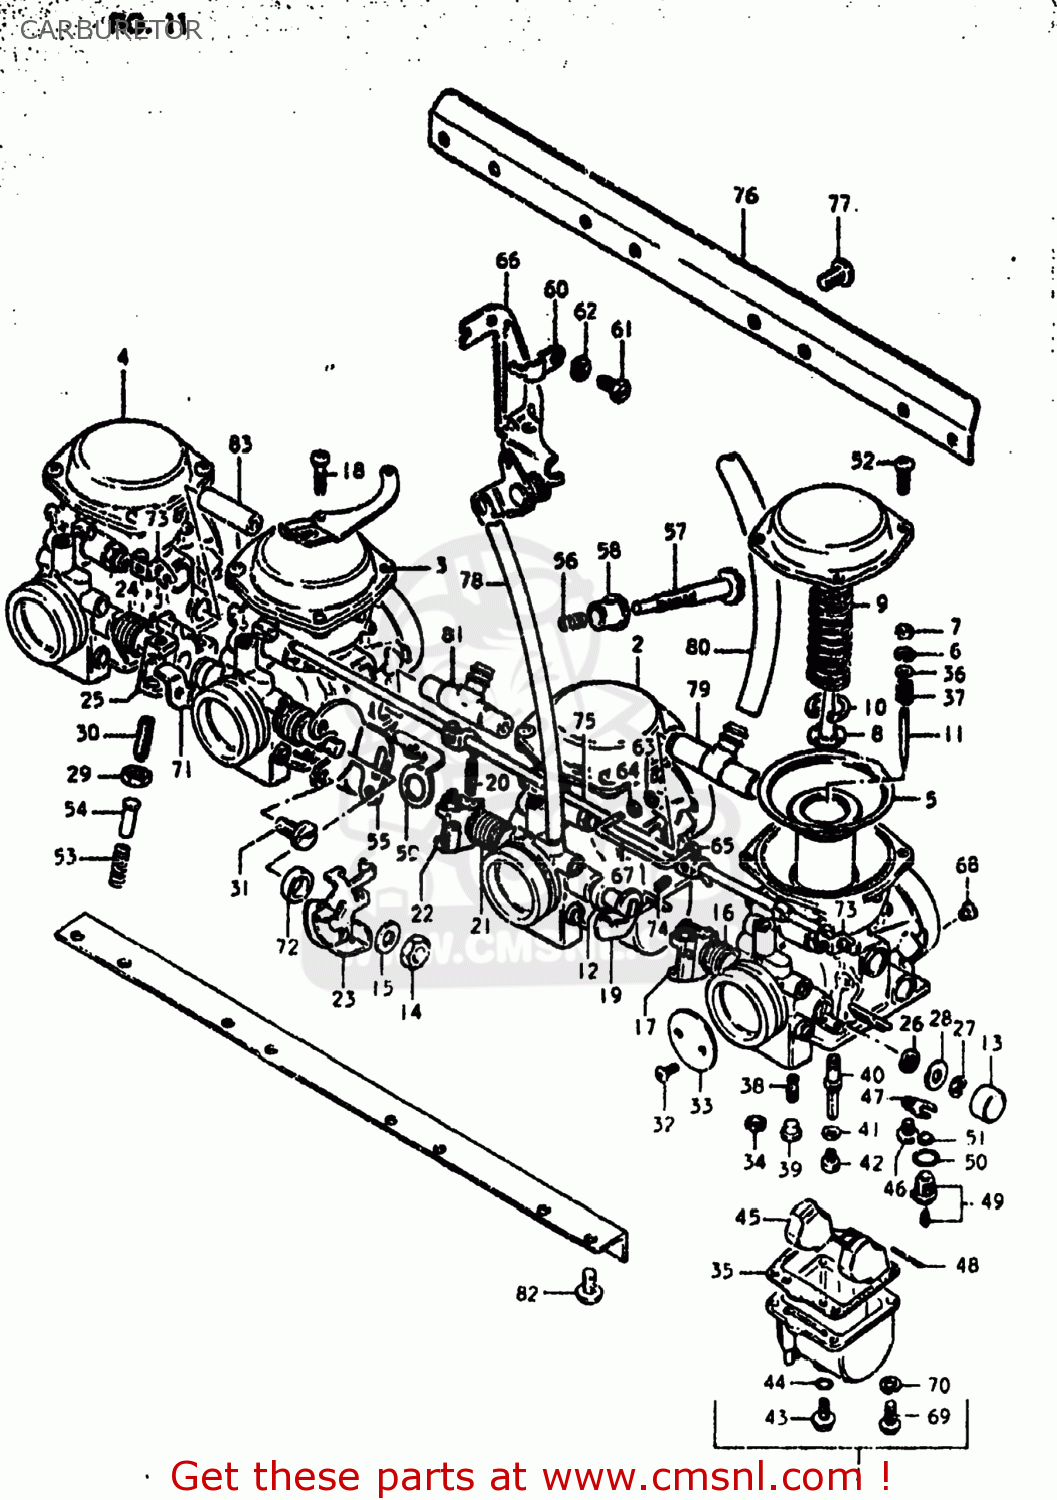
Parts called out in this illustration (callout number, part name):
1	CARBURETOR ASSEMBLY,NO.1 (A
2	CARBURETOR ASSEMBLY
3	CARBURETOR ASSEMBLY
4	CARBURETOR ASSEMBLY
5	DIAPHRAGM ASSEMBLY
6	CLIP,NEEDLE
7	RING
8	HOLDER,GUIDE
9	SPRING
10	E RING
11	NEEDLE JET
12	GASKET,THROTTLE SHAFT (NAS)
13	CAP
14	NUT
15	SCREW
16	SPRING,THROTTLE SHAFT
17	SHAFT,THROTTLE
18	SCREW
19	PIN,THROTTLE SHAFT
20	PIN,THROTTLE SHAFT
21	SPRING,THROTTLE SHAFT
22	LEVER,THROTTLE SHAFT
23	LEVER ASSEMBLY,THROTTLE
24	SPRING,THROTTLE SHAFT
25	SHAFT,THROTTLE
26	SEAL
27	E RING
28	GASKET,THROTTLE SHAFT (NAS)
29	NUT
30	SCREW
31	SCREW,THROTTLE ADJUST B
32	SCREW
33	VALVE,THROTTLE
34	GASKET (NAS)
35	GASKET,FLOAT CHAMBER (NAS)
36	WASHER
37	SPRING
38	JET,PILOT
39	PLUG,NEEDLE JET
40	JET,NEEDLE
41	WASHER,NEEDLE NOZZLE
42	JET,MAIN(92.5)
43	PLUG,DRAIN
44	GASKET (NAS)
45	FLOAT
46	SCREW
47	PLATE
48	PIN,FLOAT
49	VALVE ASSEMBLY,NEEDLE
50	O-RING,NEEDLE VALVE
51	FILTER
52	SCREW
53	SPRING,THROTTLE SCREW
54	PIN,THROTTLE LEVER
55	BRACKET,THROTTLE ADJUST
56	SPRING
57	SCREW
58	BUSH
59	BRACKET,THROTTLE ADJUST
60	BRACKET,STARTER
61	BOLT
62	LOCK WASHER
63	CAP,LEVER
64	SEAT,SPRING
65	LEVER ASSY
66	BRACKET
67	ROD,STARTER LEVER
68	JET,AIR(150)
69	SCREW
70	LOCK WASHER
71	SHAFT,THROTTLE
72	WASHER
73	LEVER
74	SCREW
75	SHAFT,STARTER
76	BRACKET
77	SCREW
78	HOSE
79	NIPPLE
80	HOSE
81	NIPPLE,CARBURETOR
82	SCREW 6X12
83	NIPPLE
